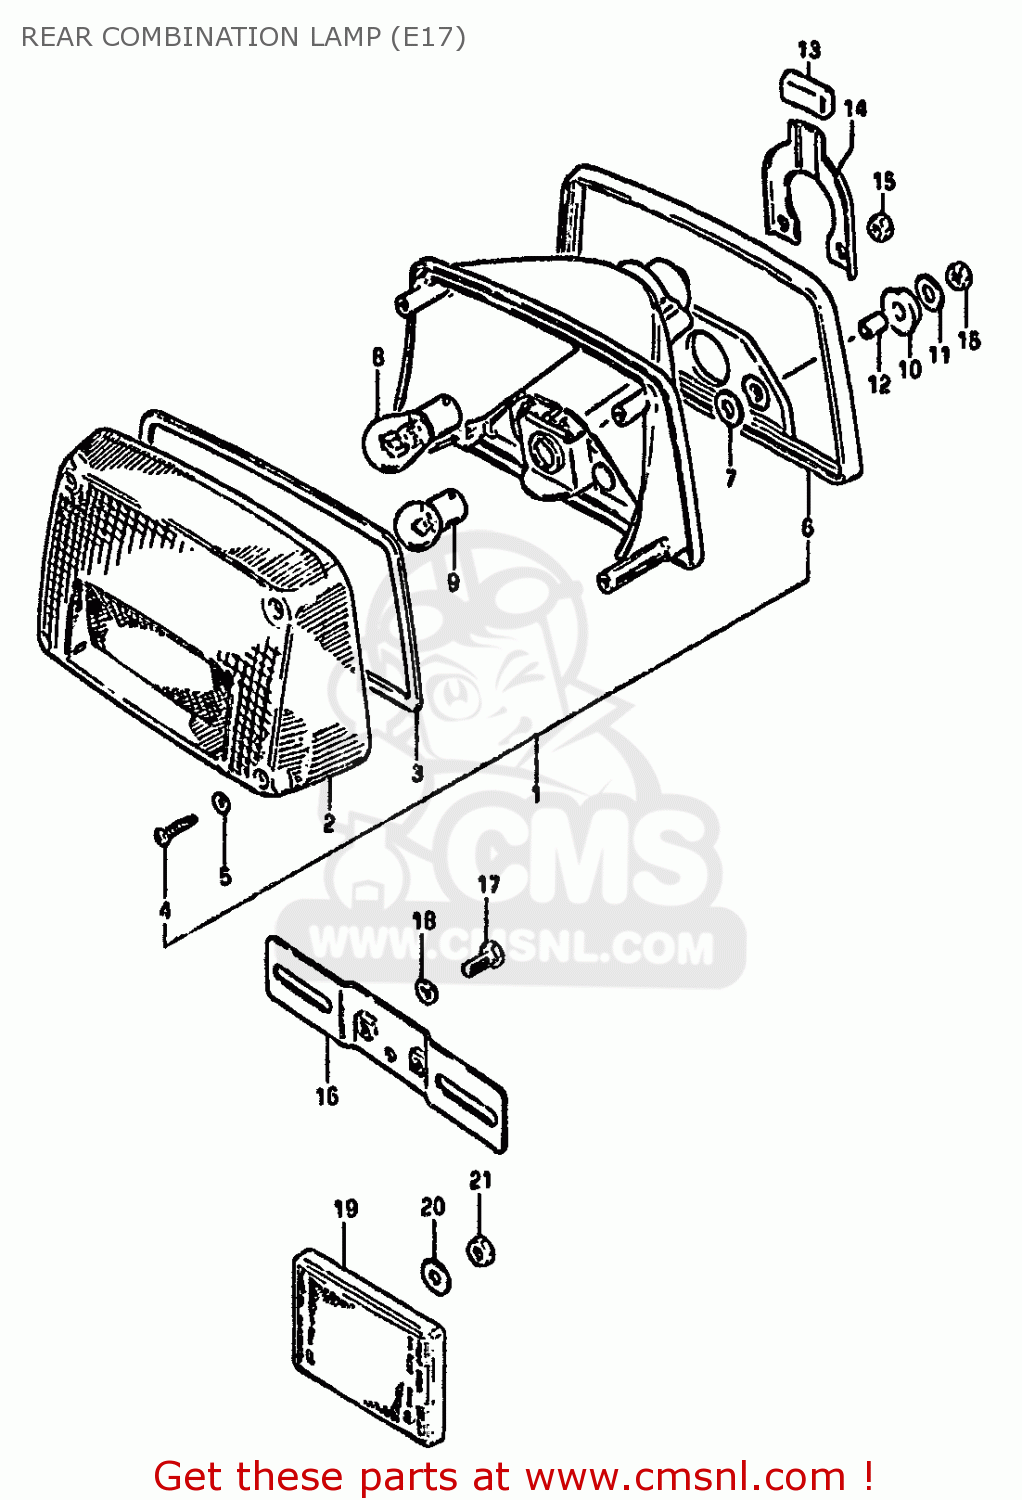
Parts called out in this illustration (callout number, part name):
1	LAMP,REAR COMBINATION
2	LENS
3	GASKET (NAS)
4	SCREW,REAR COMBINATION LAMP
5	GASKET (NAS)
6	CUSHION,REAR COMBINATION LAMP
7	WASHER,REAR COMBINATION LAMP
8	BULB(12V21/5W)
9	BULB
10	CUSHION,RR COMBINATION LAMP
11	WASHER
12	SPACER (6.4X9X10.5)
13	CUSHION,REAR COMBINATION LAMP
14	PLATE
15	NUT 6MM
16	BRACKET, LICENSE PLATE
17	BOLT
18	LOCK WASHER
19	REFLEX REFLECTOR,RR
20	WASHER (6.5X18X2)
21	NUT
